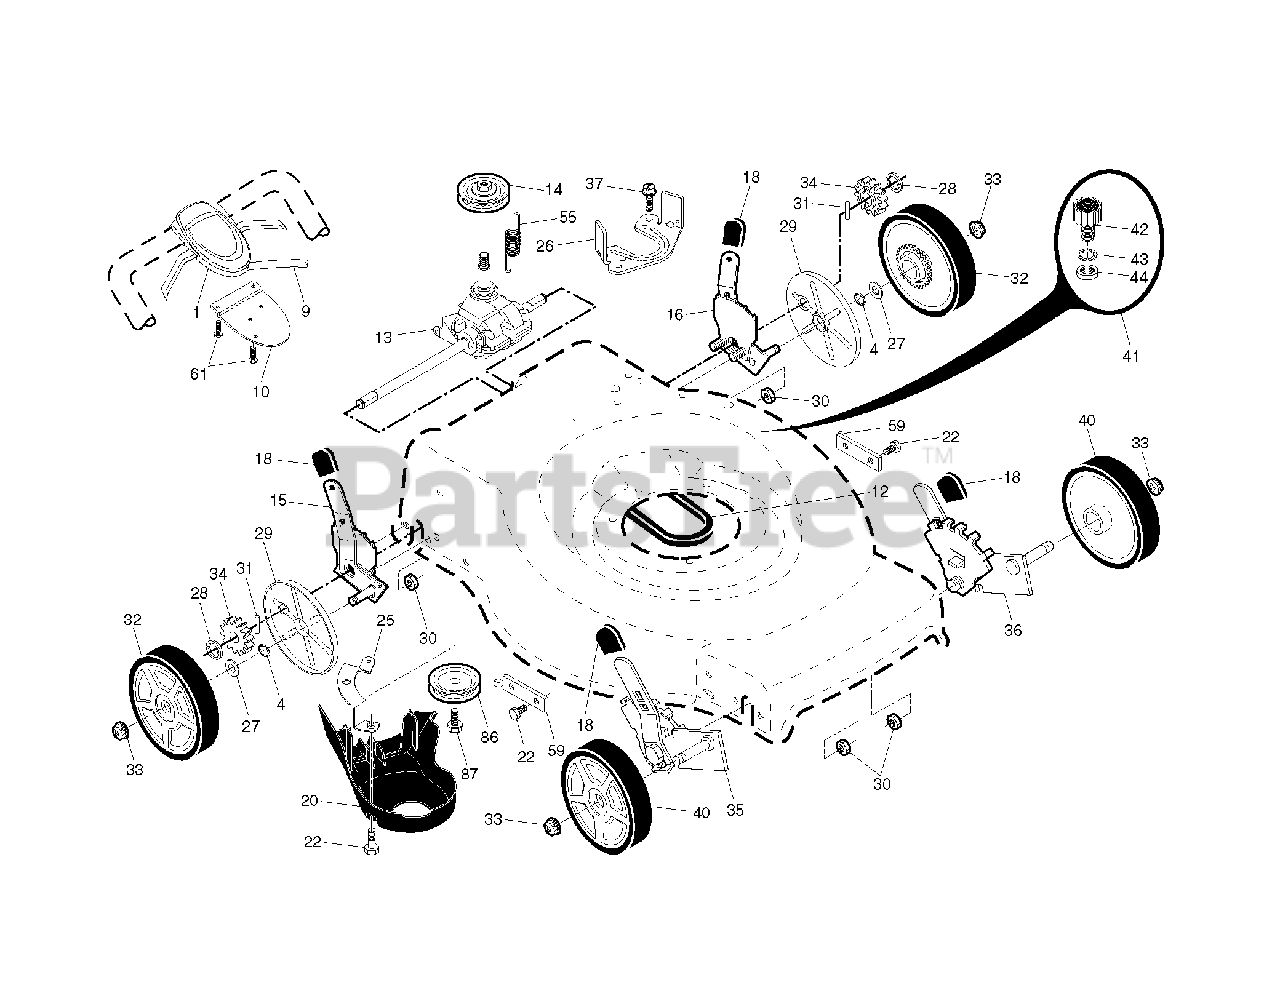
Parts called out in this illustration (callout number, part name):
1	CONTROL.EZ2.22+RG.ST.BLK/BLK
4	O-RING..070X.487.NEOPRENE
9	CABLE.DRIVE.RWD.WALK.
10	Dual Trigger Control Bracket
12	Drive Belt, RGD SS
13	TRANSMISSION.22+AWD.WALK.MOWER
14	Drive Pulley, Sm Awd/Rwd
15	Adjuster Assembly Kit, RH Front
16	Adjuster Assembly Kit, LH Front
18	SELECTOR KNOB
20	COVER.REAR.DRIVE.22+2013
22	BOLT.5/16HEX.WHS.HD
25	BRACKET.DRIVE.COVER.RGD.
26	BRACKET.TRANS.BELT.KEEPER.BZP
27	WASHER FLUT
28	E-RING 7/16 RE
29	COVER.DUST.WHEEL.INNER.WALK
30	NUT.HEX.FLANGE.1/4
31	PAWL, DRIVE
32	WHEEL.8X1.75.5SPK.RAD3.421.BU2
33	NUT.HEX.FLANGE.3/8-16.LOCKNUT
34	PINIION.14.TOOTH.RGD
35	ADJUSTER.ASM.9POS.LW.RL/RGD.FR
36	ADJUSTER.ASM.9POS.LW.RR/RGD.
41	KIT.WASH-OUT.PORT
42	FITTING, HOSE, WATER WASHOUT
43	WASHER.LOCK.INTERNAL.TOOTH
44	LOCKNUT.HEX.WITH.O-RING
55	SPRING.RETURN.AUTO.
59	BRACKET.SUPPORT.22+RWGD.BZP
61	SCREW, PHILLIPS HEAD 10 X 5/8
86	Idler Pulley, RWD Double Seal
